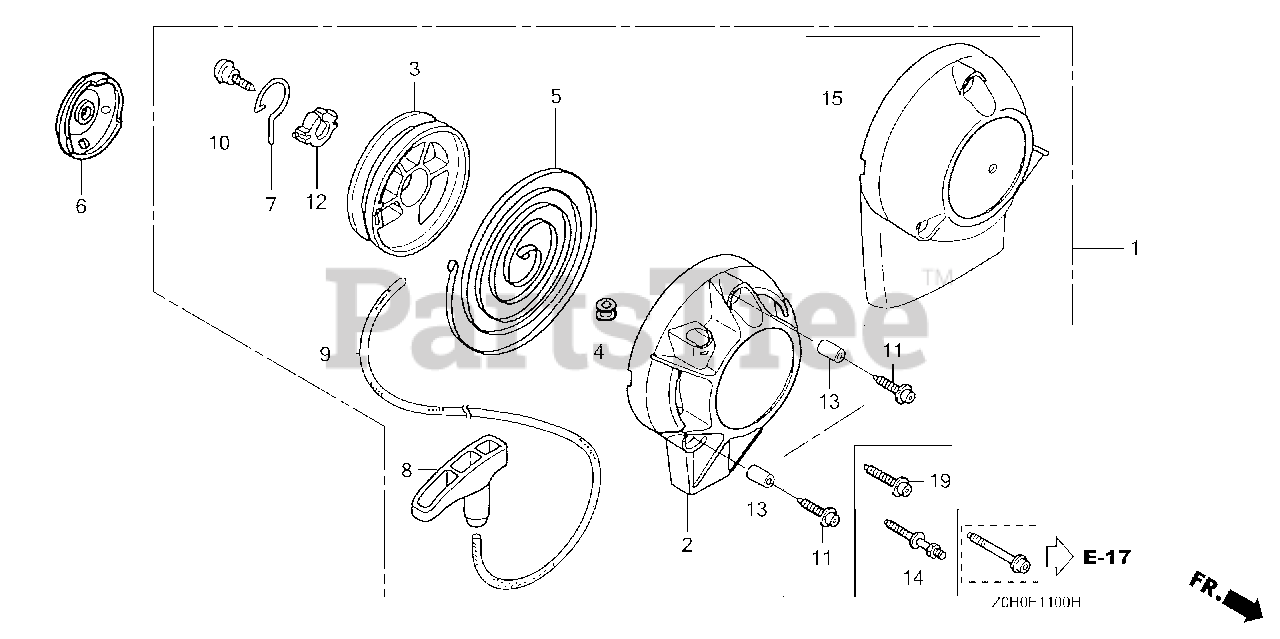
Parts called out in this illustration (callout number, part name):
1	STARTER ASSY., RECOIL
1	STARTER ASSY., RECOIL (FOR U.S.A.)
2	CASE, RECOIL STARTER
3	REEL, RECOIL STARTER
4	GUIDE, ROPE
5	SPRING, RECOIL STARTER
6	PULLEY, RECOIL STARTER
8	KNOB, RECOIL STARTER
9	ROPE, RECOIL STARTER
10	SCREW, SETTING
11	BOLT, SOCKET (5X16)
13	COLLAR A, HEAD COVER
